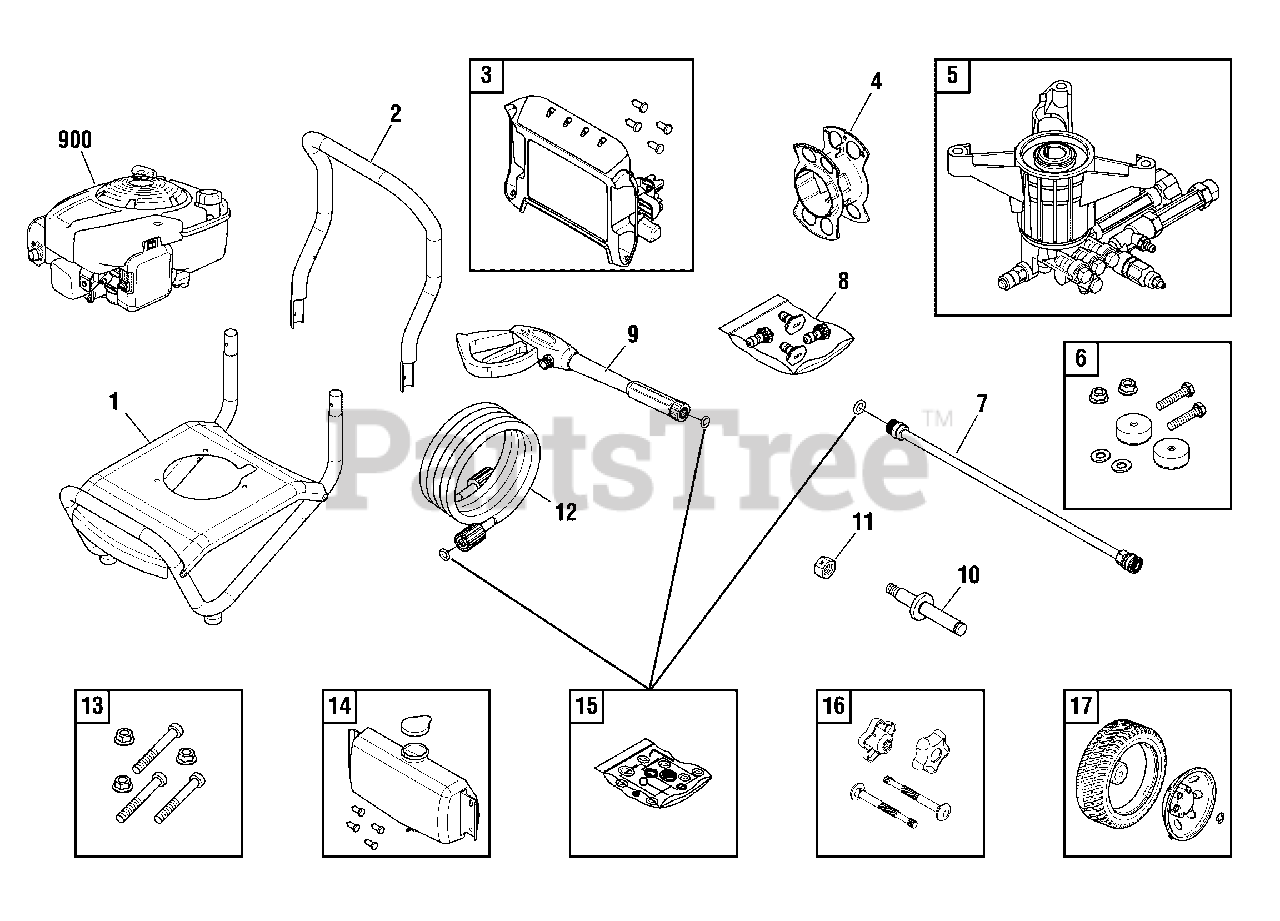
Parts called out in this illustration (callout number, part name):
6	MOUNT-VIBRATION
8	KIT-QC NOZZLES
9	GUN
12	HOSE
13	KIT-HARDWARE PUMP MOUNTING
16	KIT-HARDWARE HANDLE
17	KIT-WHEEL
900	** ENGINE
